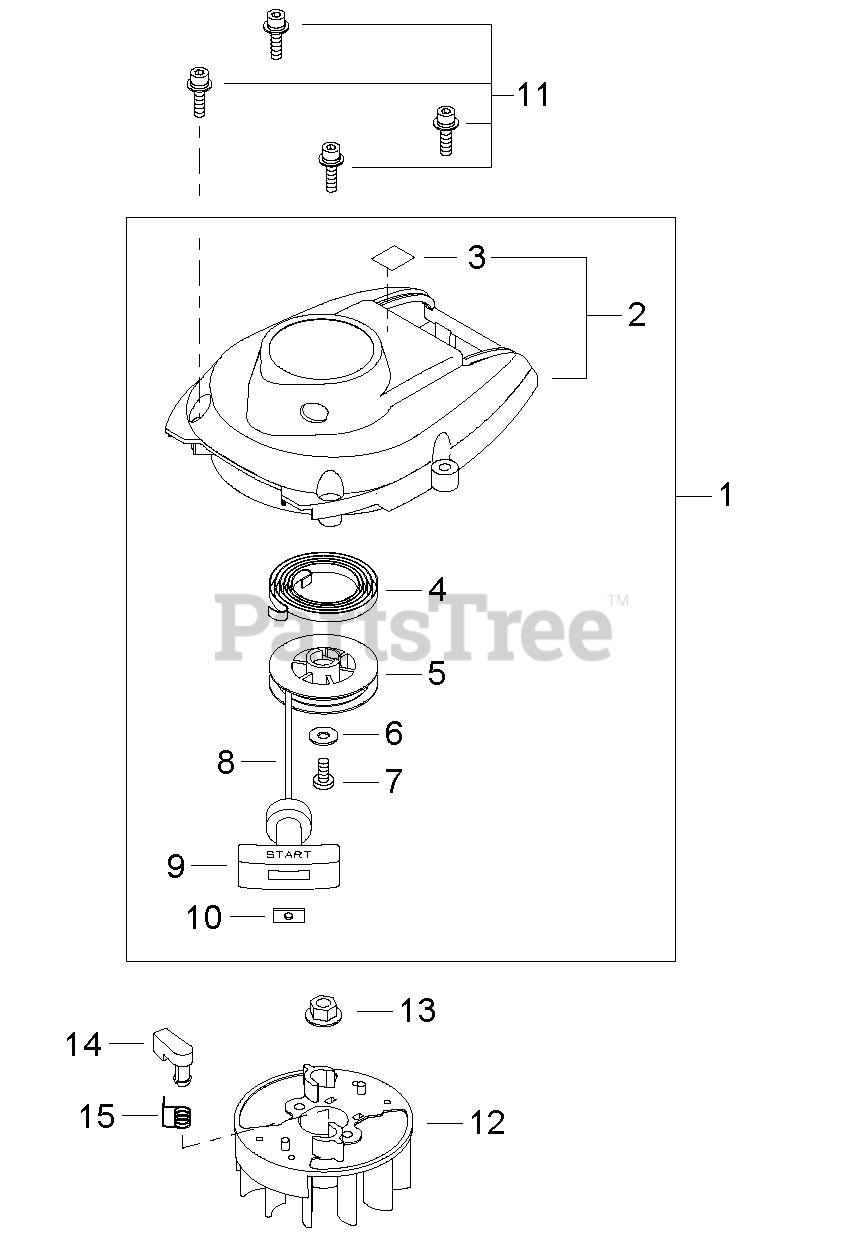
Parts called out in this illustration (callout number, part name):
1	STARTER ASSY
2	STARTER ASSY
3	LABEL - HOT SURFACE
4	SPRING, REWIND
5	REEL, ROPE
6	WASHER - 5
7	SCREW - 5
8	ROPE, STARTER
9	GRIP, STARTER
10	RETAINER, ROPE
11	SCREW - 5X20
12	FLYWHEEL
13	NUT - 8
14	PAWL, STARTER
